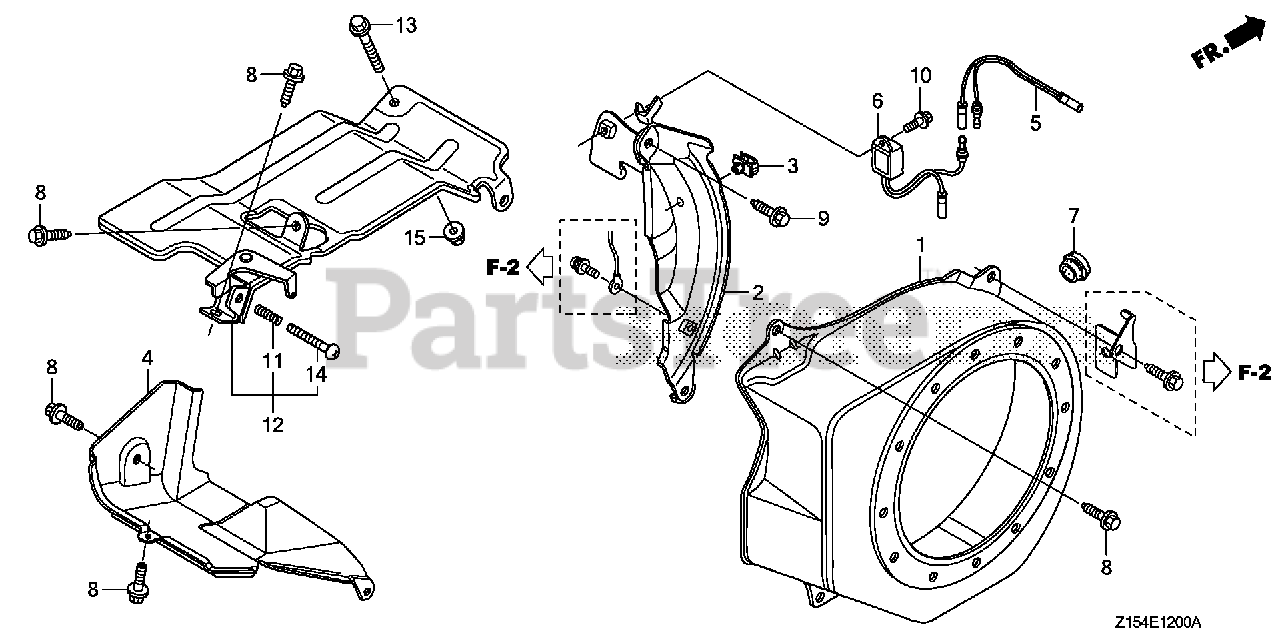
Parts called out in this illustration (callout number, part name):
1	COVER, FAN *NH1* (BLACK)
2	PLATE, SIDE (OIL ALERT)
3	CLAMP, CORD
5	SUB-HARNESS
6	ALERT UNIT, OIL
7	GROMMET, DRAIN HOLE
8	BOLT, FLANGE (6X12) (CT200)
9	BOLT, FLANGE (6X20) (CT200)
10	BOLT, FLANGE (6X8)
